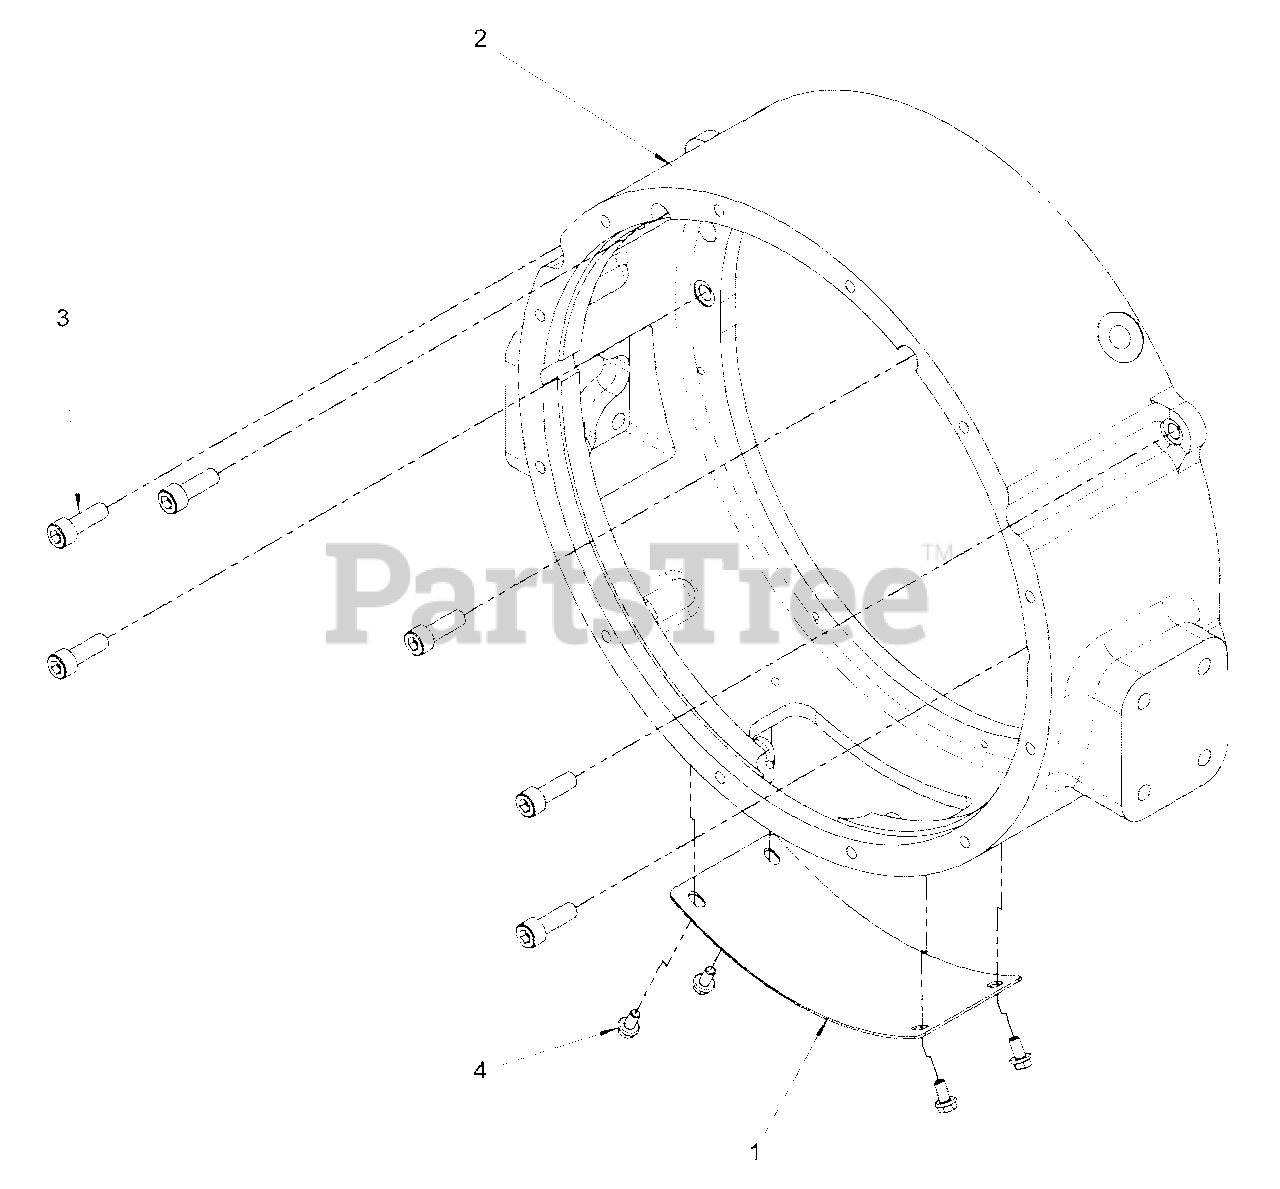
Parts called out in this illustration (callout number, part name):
1	COVER PLATE-B/W
2	HOUSING, SAE 3
3	BOLT
4	BOLT
